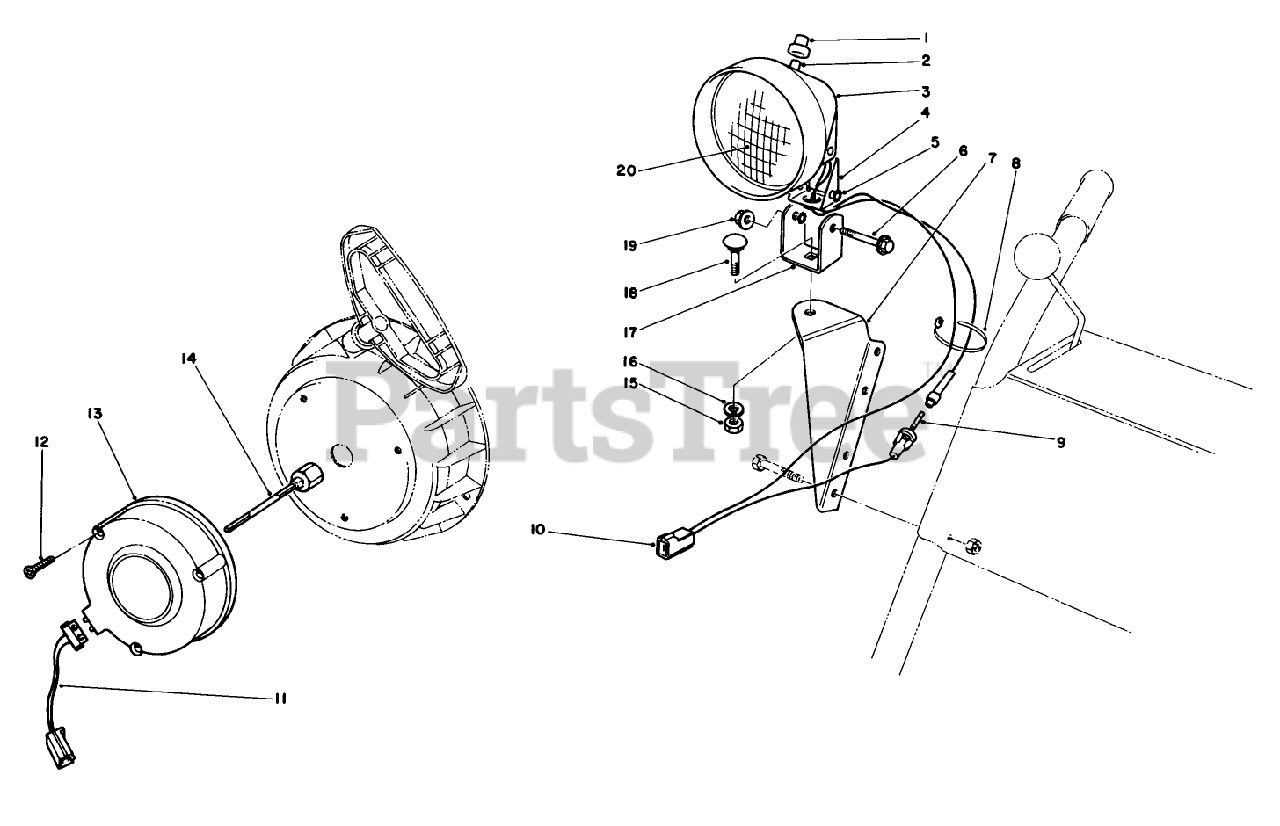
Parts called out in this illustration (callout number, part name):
1	BOOT-SWITCH
5	WASHER-LOCK
6	SCREW-HH
7	MOUNT-LAMP
8	TIE-CABLE
9	Fuse-7-1/2 Amp
10	WIRE ASM
13	TECUMSEH 1A183-69
15	NUT-HEX
16	WASHER-LOCK
18	BOLT-CARR
19	NUT-HF
20	BEAM-SEALED
